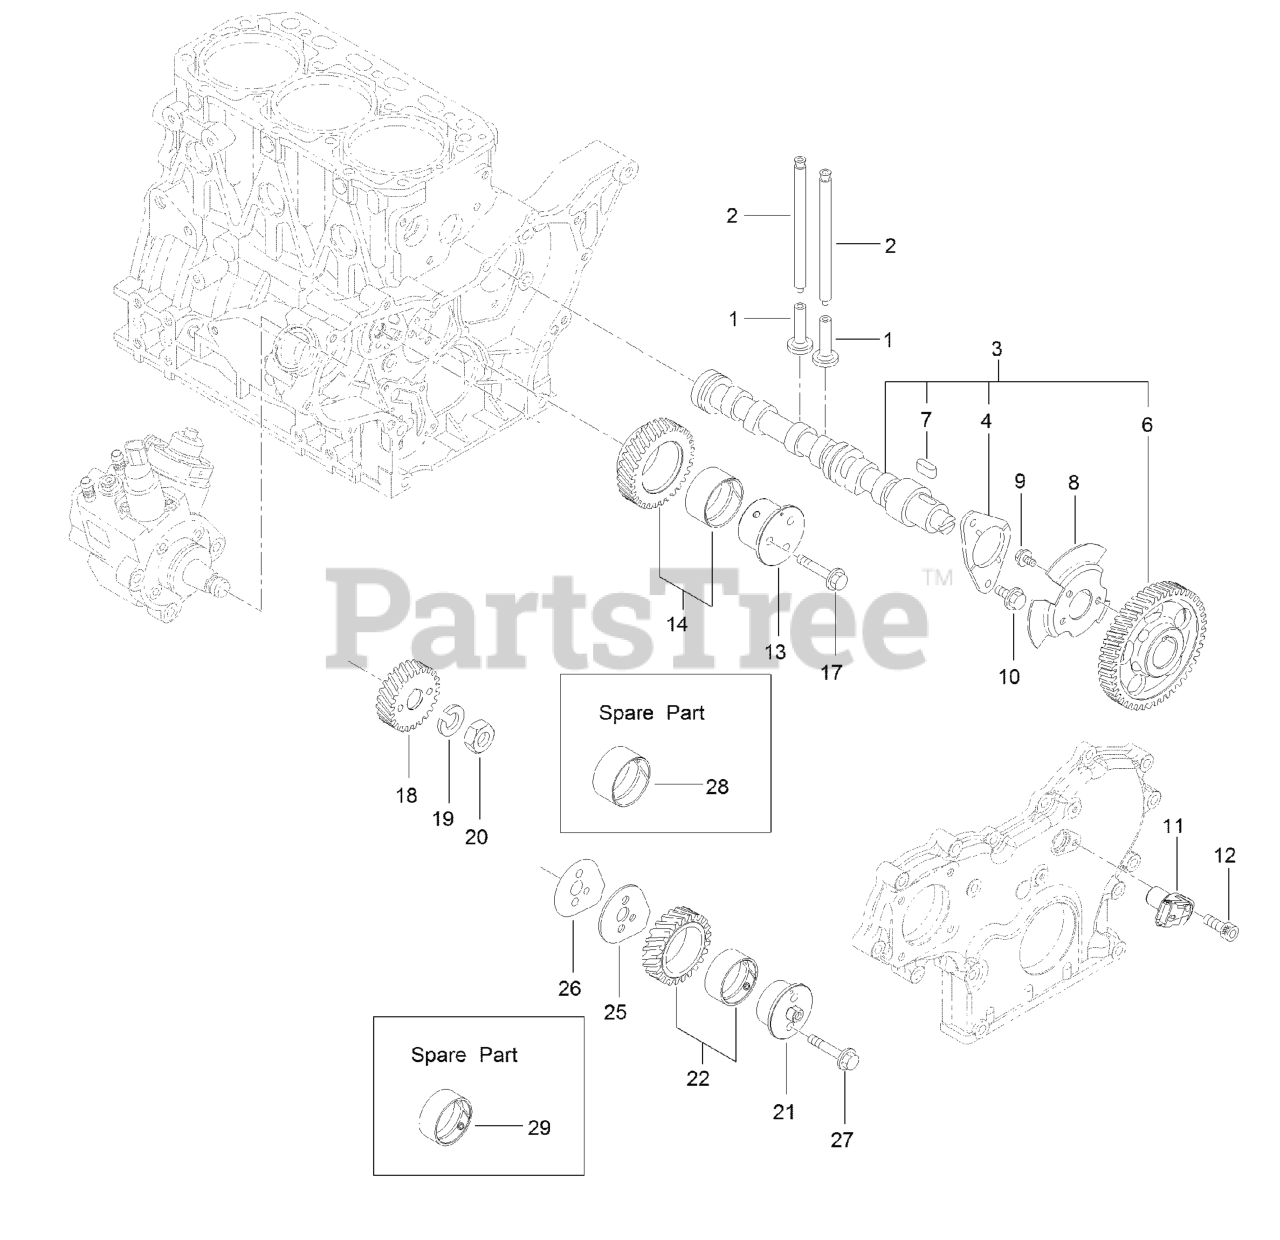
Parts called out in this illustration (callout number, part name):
2	ROD-PUSH
3	CAMSHAFT ASM
4	METAL-THRUST
6	Gear-Camshaft
8	PULSER-CAMSHAFT
11	SENSOR-REV, GEAR
13	Shaft-Idle, Gear A
14	IDLE GEAR A ASM
18	Gear-Pump, Supply
19	Washer-Spring
20	Nut-Lock
21	Shaft-Idle, Gear B
22	IDLE GEAR B ASM
25	Plate-Idle, Shaft
26	Gasket-Idle, Shaft B
28	BUSHING
29	BUSHING
